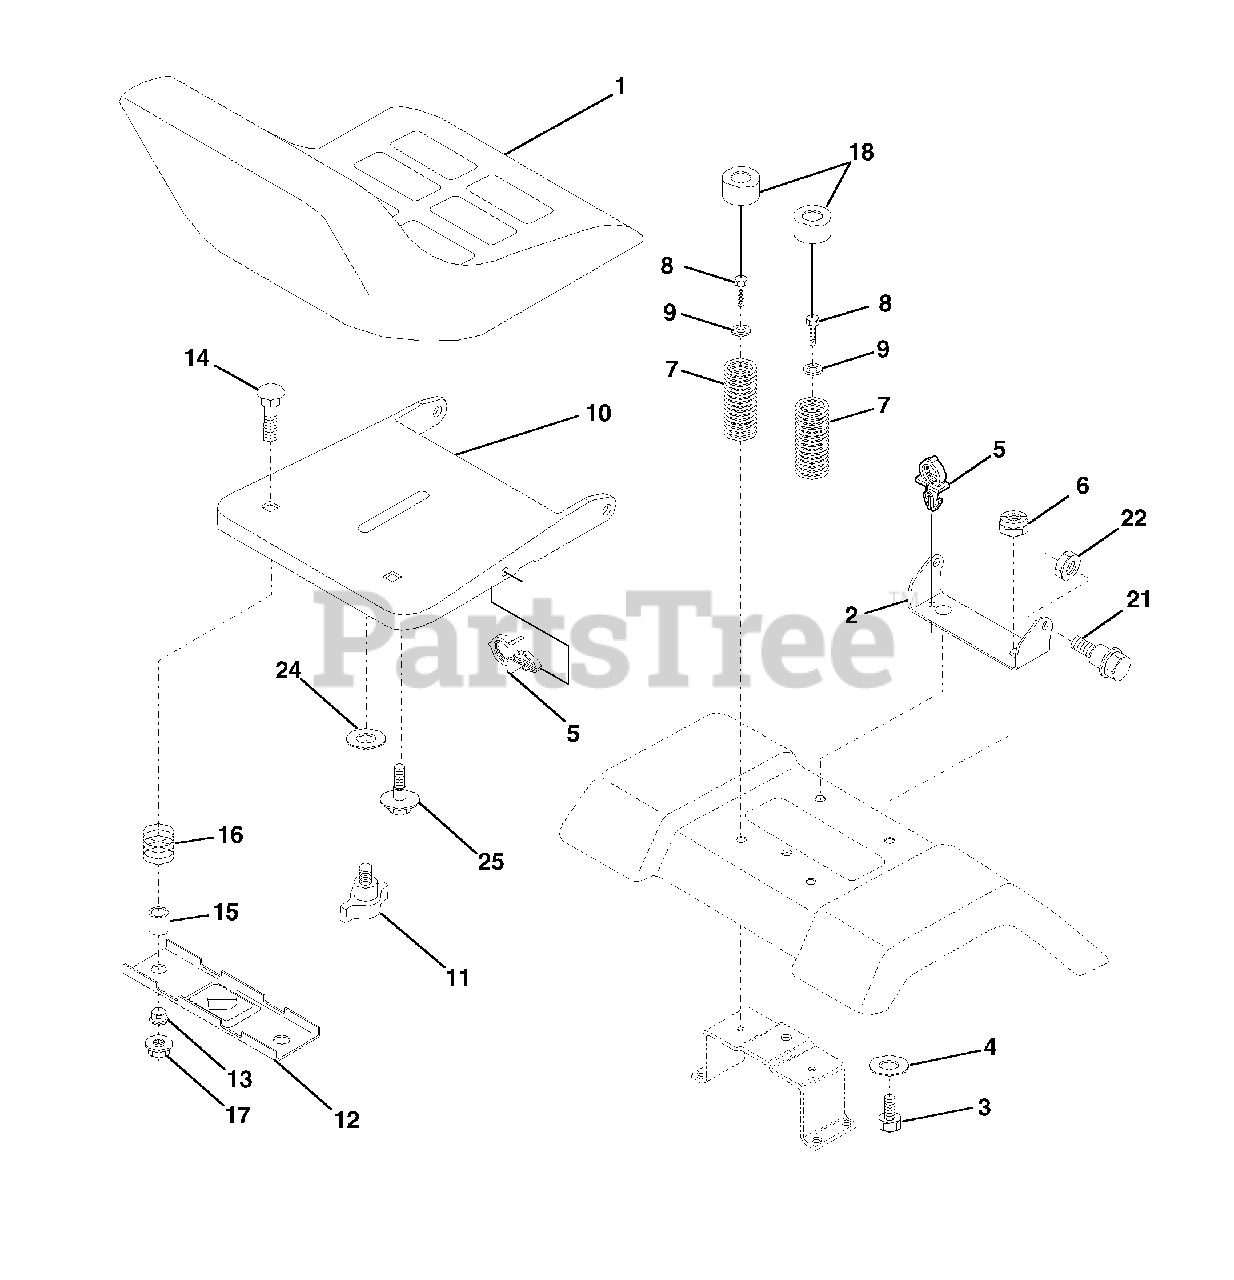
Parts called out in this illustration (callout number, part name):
1	Seat
2	Bracket Pivot Seat 8 720
3	Bolt Fin Hex 3/8-16unc X 1
4	Washer 13/32 X 1 X 10 Ga
5	Clip Push-In
6	Nut Hex w/Ins. 3/8-16 Unc
7	Spring Seat Cprsn 2 250 Blk Zi
8	Screw Thdrol 3/8-16 X 1 Ty-tt
9	Washer 13/32 X 1 X 14 Ga.
10	Pan Seat
11	Knob Seat Adj Wingnut
12	Bracket Mounting Switch
13	Bushing Snap Blk Nyl 50 Id
14	Bolt Rdhd Sqnk 1/4-20x1-1/2
15	Spacer Split 28x 96 Yel Zinc
16	Spring Cprsn 1 27 Blk Pnt
17	Nut Lock 1/4 Lge Flg Gr 5 Zinc
18	Cap Spring Seat
21	Bolt Shoulder 5/16-18 Unc
22	Nut Hex Lock W/Ins 5/16-18
24	Washer 17/32 X 1-3/16 X 12 Ga.
25	Bolt Shoulder 5/16-18 X 62
